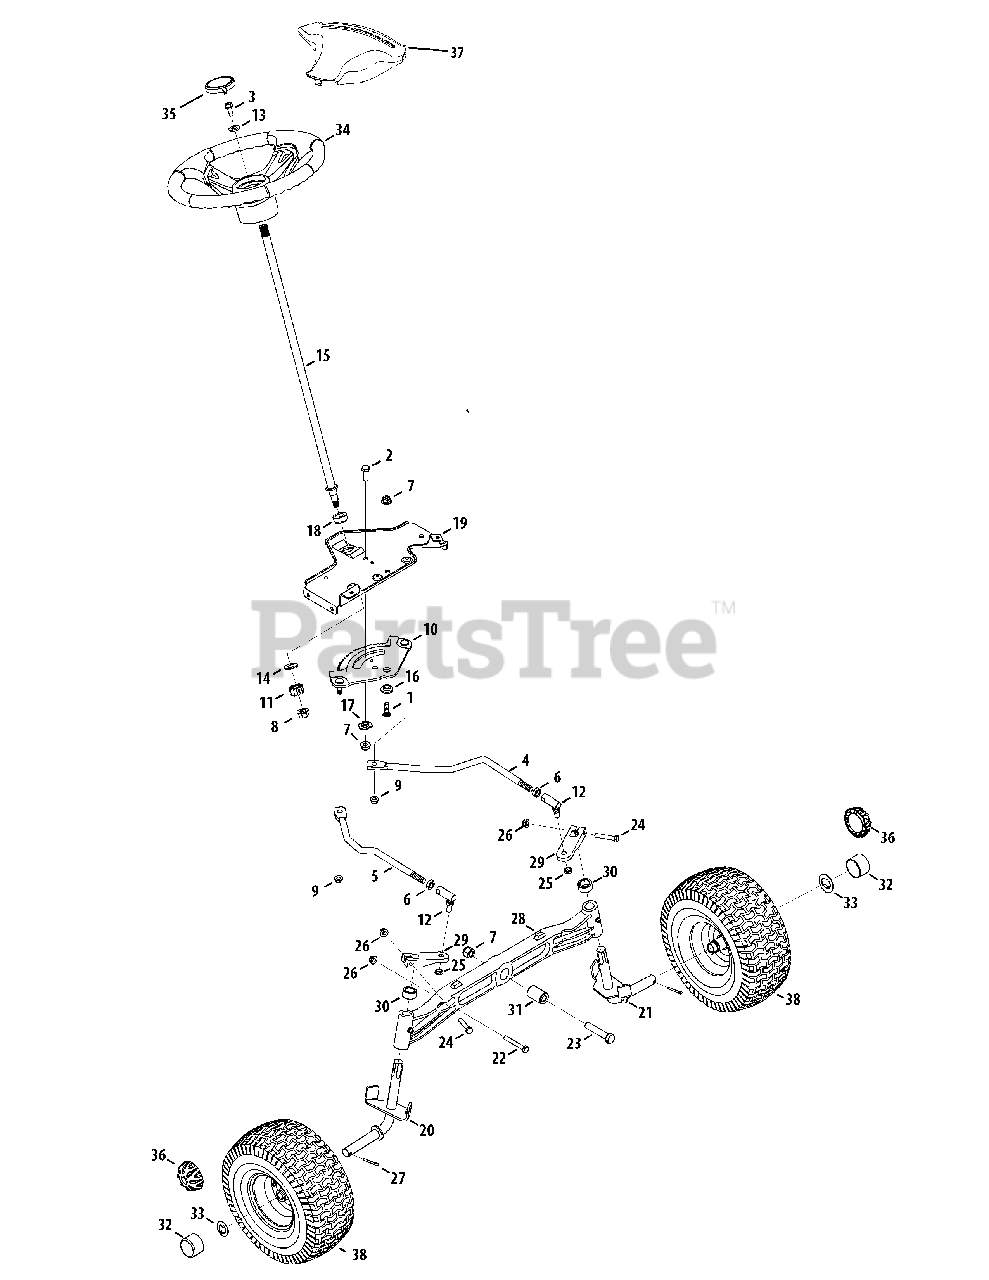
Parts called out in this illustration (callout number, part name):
1	Screw, 3/8-16 x 1.0
2	Hex Screw 3/16 x 1.00
3	Hex Screw 5/16-18 x 1.00 Special
4	Link, Drag LH
5	Link, Drag RH
6	Hex Jam Nut 7/16-20
7	Flange Lock-Nut 3/8-16 Gr. F Nylon
8	Flange Lock Nut, 7/16-20
9	Hex Flange L-Nut 5/16-18
10	Steering Gear, 11/90 Ratio
11	Steering Pinion Gear
12	Ball Joint, 7/16 - 20
13	Flat Washer .406 ID x .875 DE x .105
14	Fl. Washer .510 x 1.120 x .060
15	Steering Shaft .625 OD x 24.25
16	Shoulder Spacer .385 x 1.25 x .3025
17	Spacer .38x 1.375 Special
18	Hex Flange Bearing 5/8
19	Steering Support Bracket
20	Axle Ass’y RH .750 Dia. (54" Deck)
21	Axle Ass’y LH .750 Dia. (54" Deck)
22	Hex Bolt 5/16-18 x 2.25
23	Hex Cap Screw, 3/8-16 x 2.5
24	Hex Screw 5/16-18 x 1.75" Lg.
25	Hex Cent L-Nut 3/8-24
26	Flange Locknut 5/16-18 Gr. F, Nylon
27	Cotter Pin 5/32" Dia.
28	Pivot Bar (cast)
29	Steering Block
30	Spacer .710 ID x .125 OD x .56
31	Spacer .385 x 1.0 x 1.5075
32	Hub Cap
33	Flat Washer .350 x 1.559 x .062
34	Steering Wheel, Standard Grip
34	Steering Wheel, Softgrip
35	Steering Wheel Cap (sprig)logo
36	Hub Cap
37	Steering Wheel Cover (w/sprigs)
38	Wheel Complete
